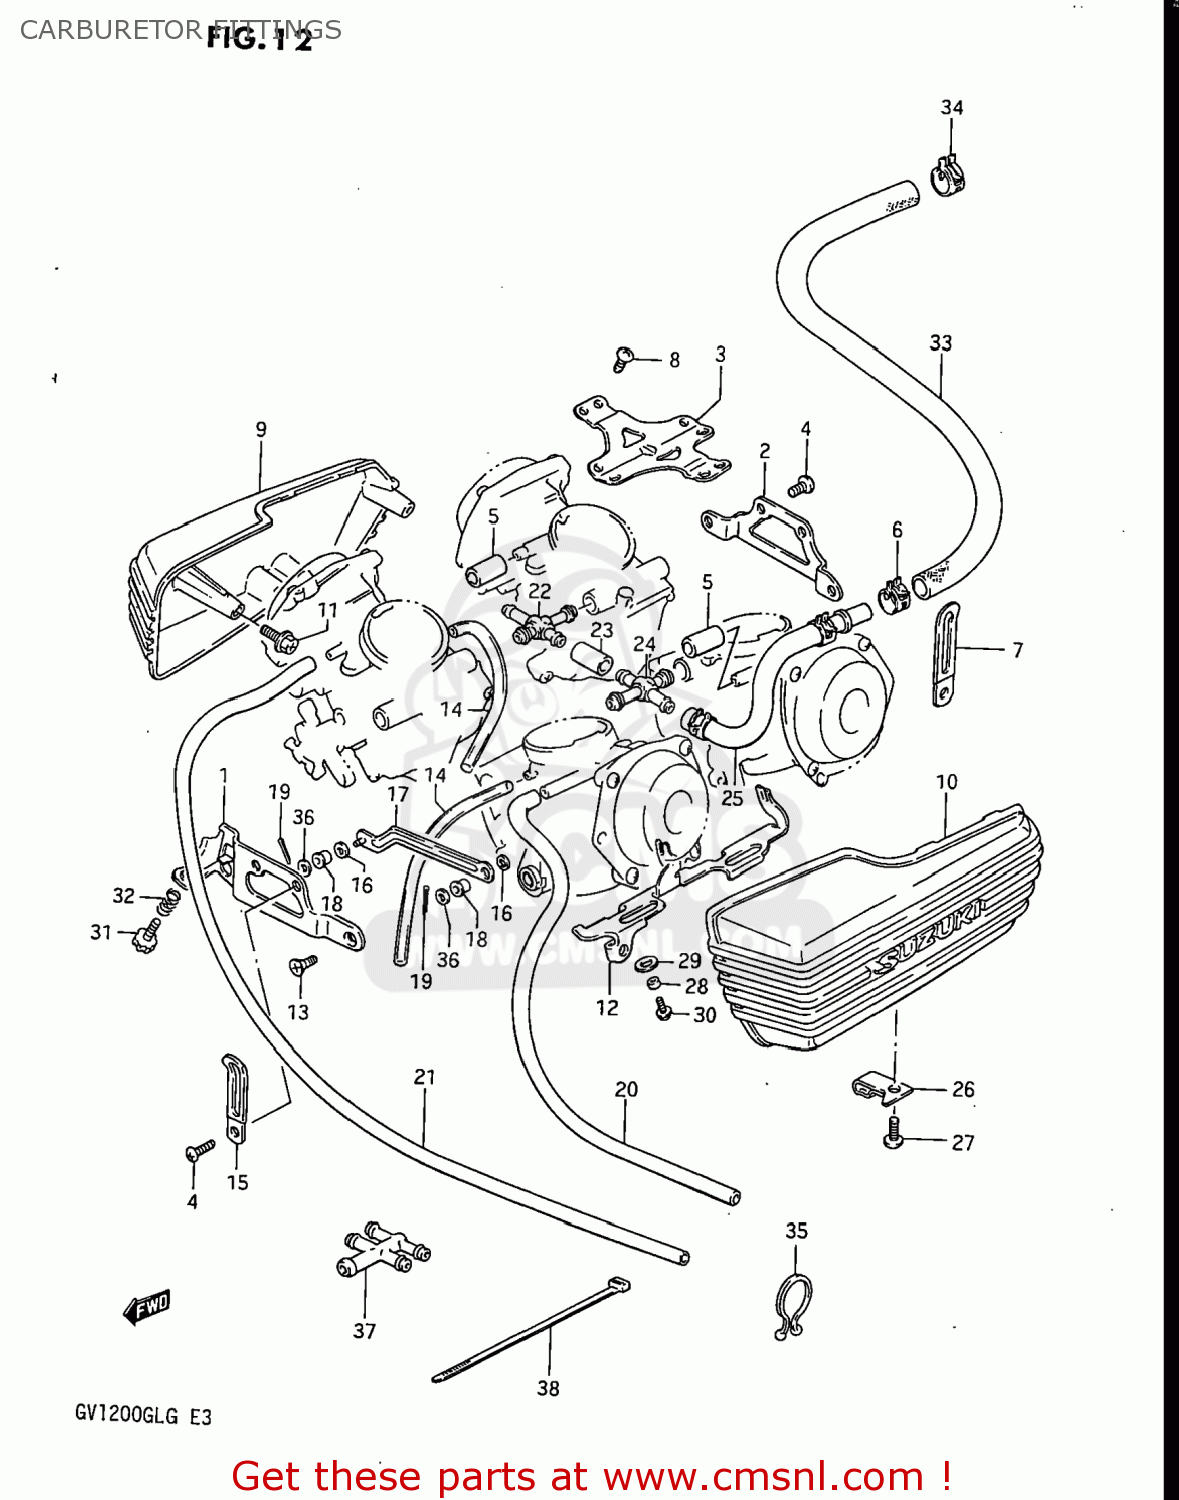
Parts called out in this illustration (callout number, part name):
1	PLATE
2	PLATE
3	PLATE
4	SCREW
5	HOSE
6	CLIP
7	CLIP
8	SCREW 5X10
9	COVER,CARBURETOR,RIGHT
10	COVER,CARBURETOR,LEFT
11	BOLT
12	LEVER
13	SCREW
14	HOSE
15	CLAMP L:35
16	WASHER,CHOKE LEVER
17	PLATE
18	RING
19	COTTER
20	HOSE
21	HOSE
22	NIPPLE
23	HOSE
24	NIPPLE
25	HOSE ASSEMBLY
26	PLATE
27	SCREW
28	RING
29	WASHER
30	SCREW
31	ADJUSTER,THROTTLE
32	SPRING
33	HOSE
34	CLAMP
35	CLIP
36	WASHER
37	SPRING
38	CLAMP
